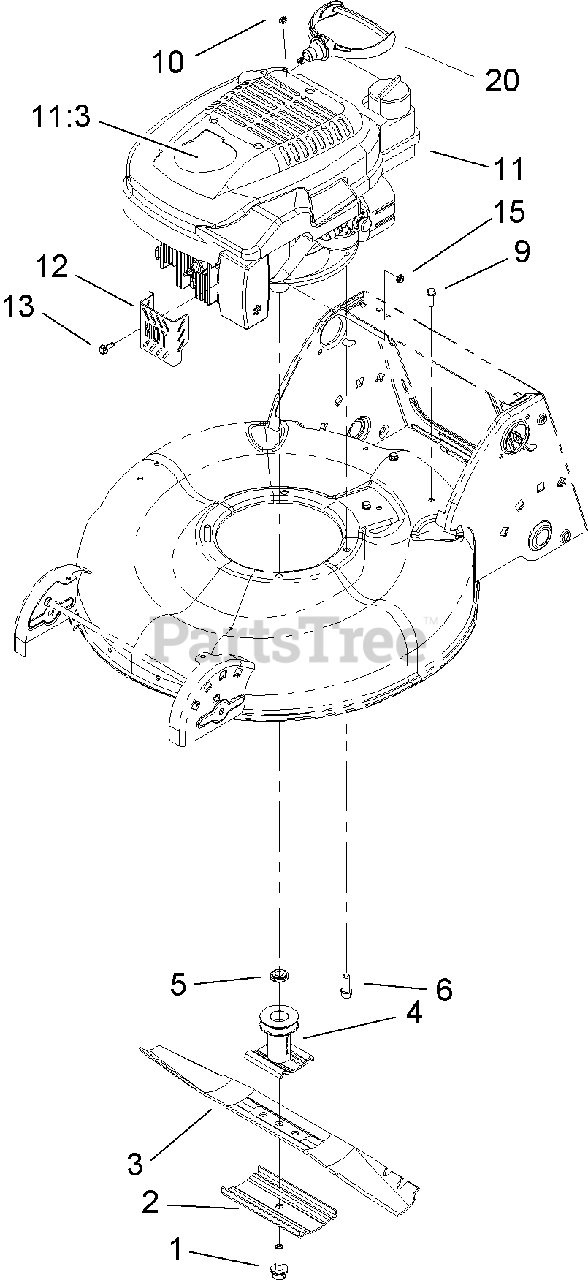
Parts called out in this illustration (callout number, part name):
1	BOLT-BLADE
2	SUPPORT-BLADE
3	BLADE-21 IN
4	BLADE DRIVER ASM
5	Spacer-Driver
6	SCREW
9	SCREW-HWH
10	STOP-ROPE
11:3	DECAL-RECOIL
12	GUARD-MUFFLER
13	SCREW-HWH
15	NUT-KEPS
20	HANDLE-RECOIL
